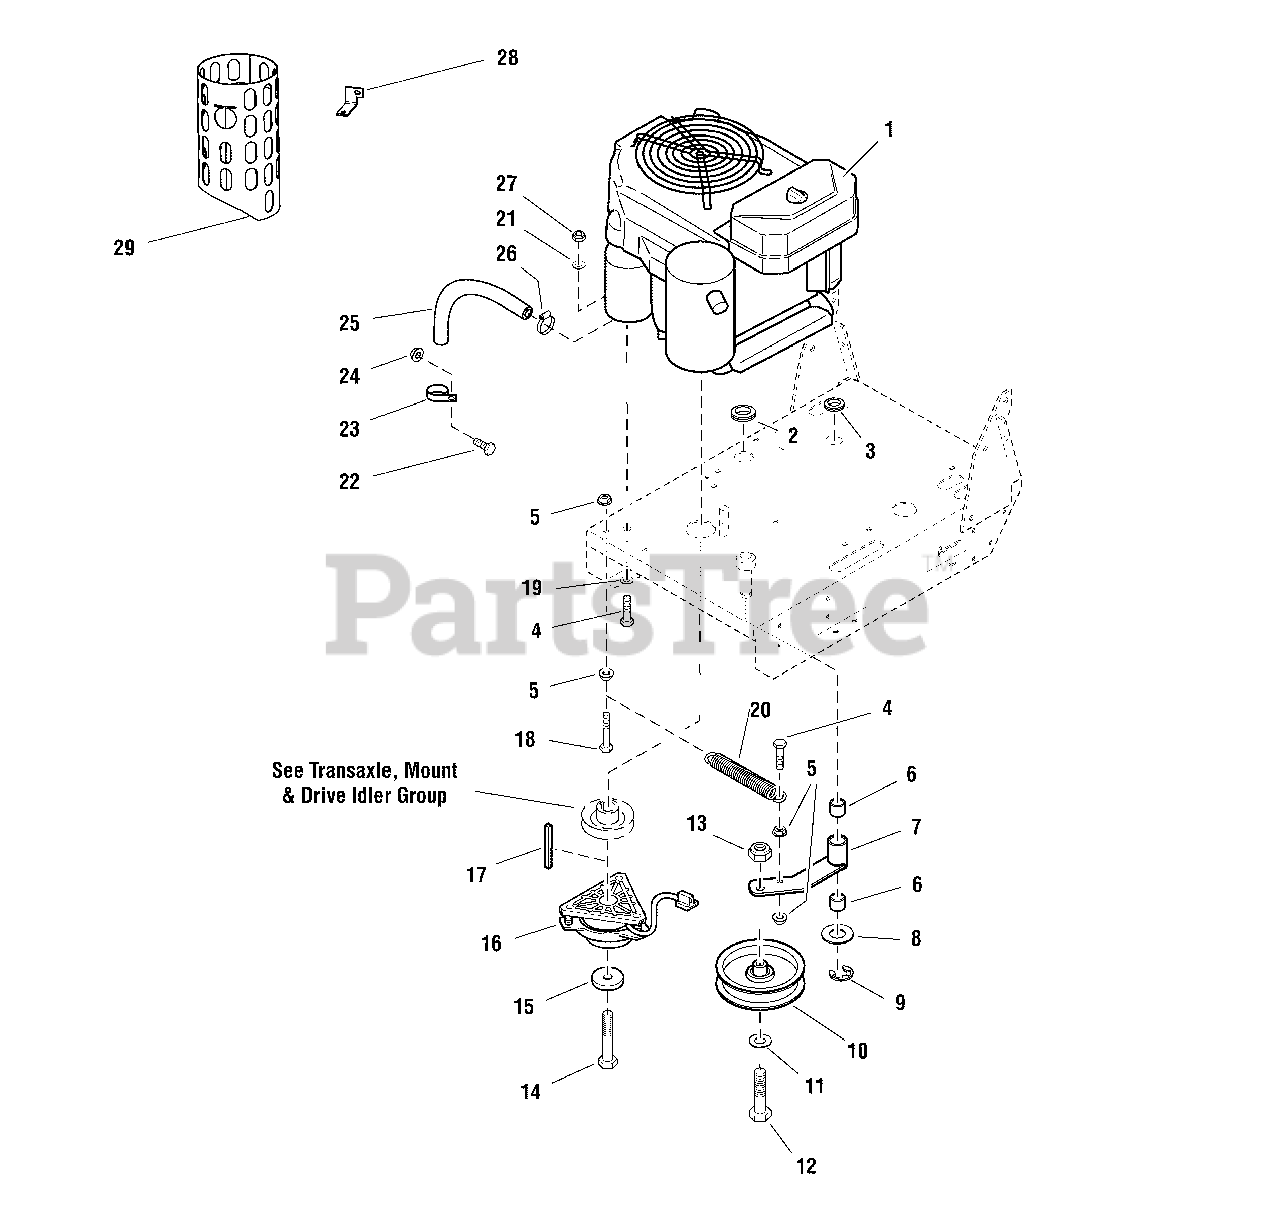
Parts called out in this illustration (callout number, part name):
1	* ENGINE, 13HP KAW ELEC START Mod. FH381V-BS28-R
2	GROMMET, 7/8
3	GROMMET, 1/2
4	BOLT, 5/16-18 X 1-1/2" GD5 YZ
5	NUT, 5/16-18 Hex Large Serrated Flange
6	BUSHING, BRASS, 3/4 X 1 X 1
7	DECK DRIVE IDLER ARM
8	WASHER, 3/4" SAE
9	C-CLIP
10	IDLER PULLEY
11	WASHER, 1/2 SAE
12	BOLT, 1/2-20 X 2-1/2" GD5 CZ
13	NUT, Hex, Nylon Lock, 1/2-20
14	BOLT, CRANKSHAFT, 7/16"X2.75
15	SPACER, .45 x 1.62 x .37
16	CLUTCH,#504586, ELECTRIC, OGURA JD-11
17	KEY, 1/4 SQ. X 2
18	BOLT, 5/16-18 X 2-1/4" GD5 YZ
19	WASHER, 5/16" SAE
20	SPRING, Extension
21	WASHER, 5/16" SAE
22	BOLT, 5/16-18 X 3/4 GD5
23	CLAMP, HOSE, 1.000 DIA.
24	NUT, 5/16-18 HEX SERRATED FLANGE (SMALL)
25	HOSE, 1/2" PUSH-ON, 10.50"
26	CLAMP, #6 HOSE, STAINLESS
27	NUT, 5/16-18 HEX NYLON LOCK
28	BRACKET, MUFFLER GUARD - RED
29	WELD, MUFFLER GUARD - RED
